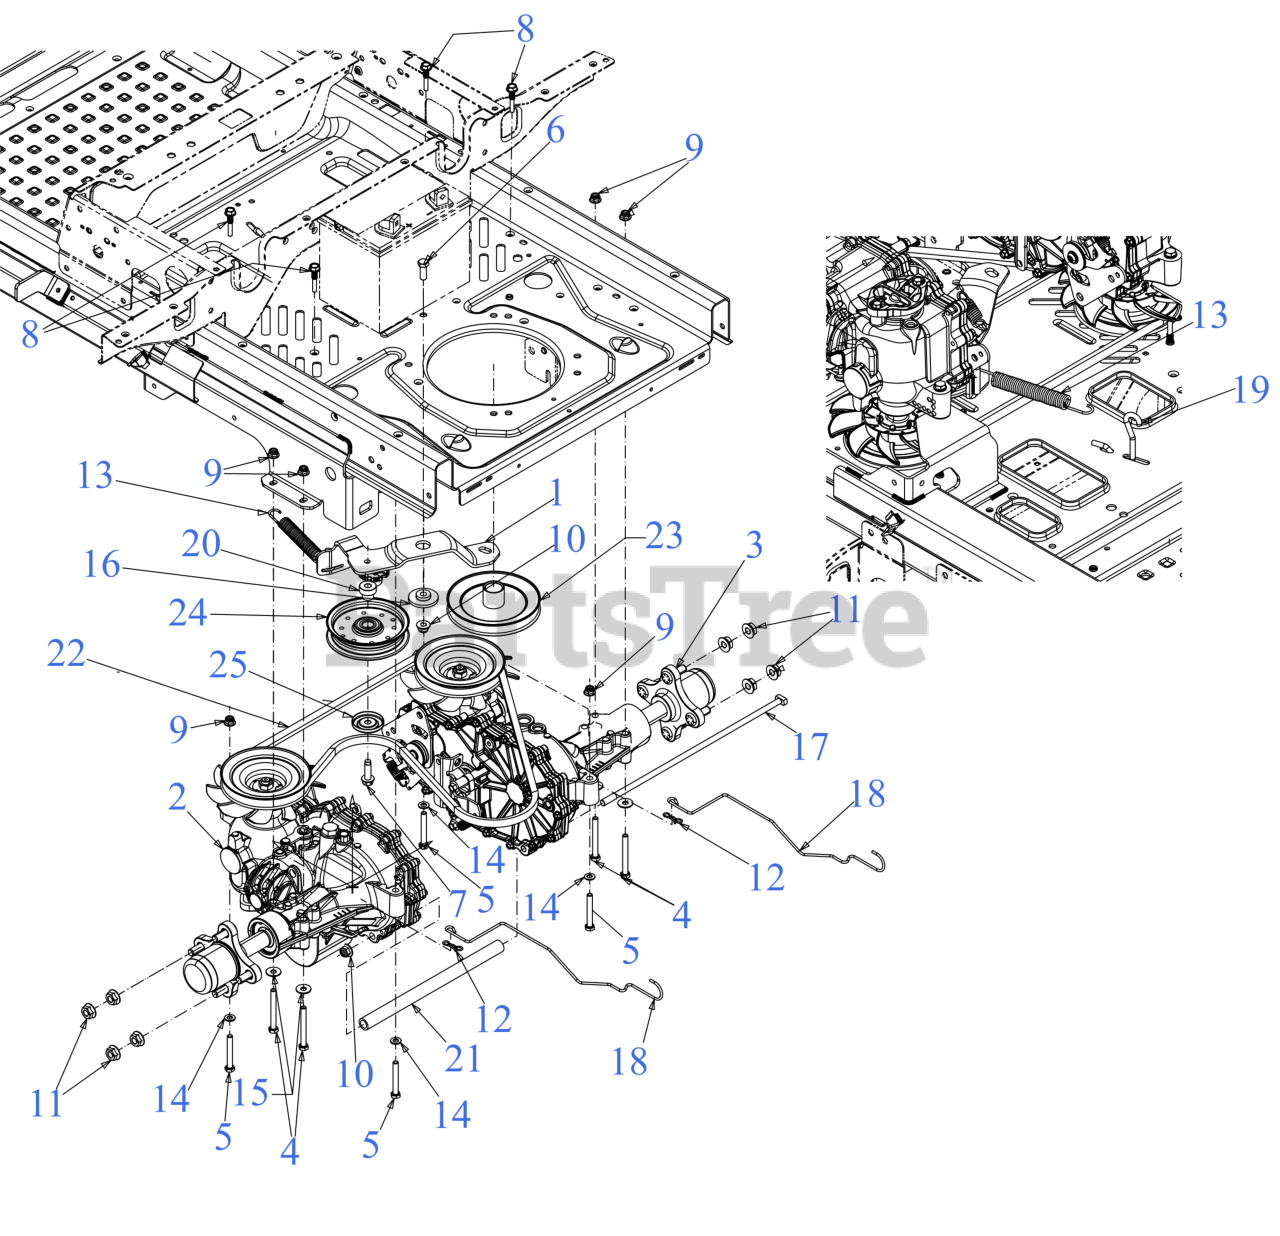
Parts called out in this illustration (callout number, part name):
1	IDLER BRACKET ASSEMBLY
2	TRANSMISSION (LH)
3	TRANSMISSION (RH)
4	HEX SCREW 5/16-18 x 2.75
5	HEX SCREW 5/16-18 x 2.25 GR5
6	SCREW 3/8-16 x 1 GR5
7	SCREW 3/8-16 X1.250
8	BELT KEEPER ROD .25 x 1.585
9	FLANGE LOCK NUT 5/16-18
11	HEX FLANGE NUT 7/16-14
12	BOW TIE COTTER PIN 1/4-5/16
13	EXTENTION SRING .75 DIA. x 6.85
14	FLAT WASHER
15	FLAT WASHER
16	SHOULDER SPACER
17	SUPPORT TUBE ROD
18	HYDRO BYPASS ROD
19	IDLER SPRING HOOK
20	SHOULDER SPACER
21	TRANSMISSION SPACER .75OD x 11.31
22	TRANSMISSION DRIVE BELT A x 67
22	Cub Cadet TRANS DRIVE BELT A x 67 RZT
22	Troy-Bilt TRANSMISSION DRIVE BELT
23	TRANMISSION DRIVE PULLEY
24	IDLER PULLEY 4.25 DIA
25	IDLER PULLEY CAP
